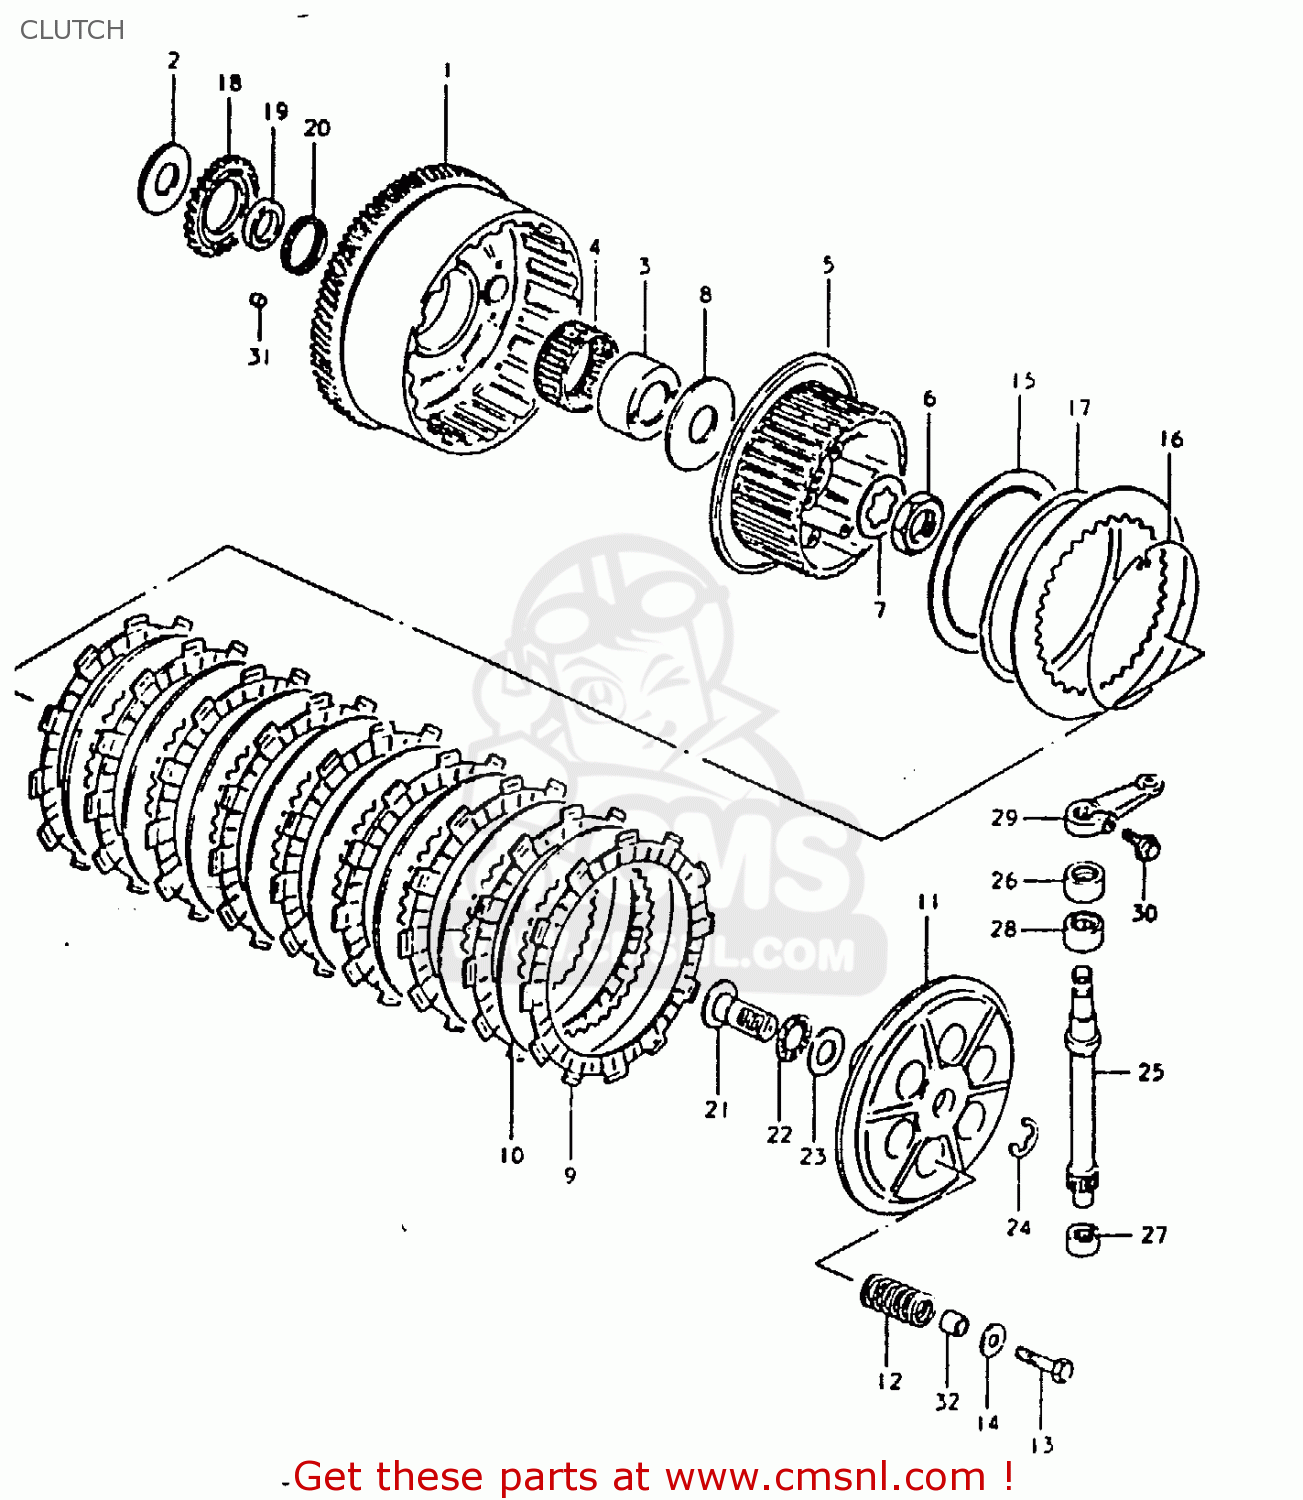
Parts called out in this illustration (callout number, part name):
1	GEAR ASSEMBLY,PRIMARY DRIVE
2	WASHER
3	SPACER
4	BEARING
5	HUB,CLUTCH SLEEVE
6	NUT
7	WASHER,LOCK
8	WASHER(25X66X3.5)
9	PLATE,CLUTCH DRIVE (MCA)
10	PLATE,CLUTCH DRIVEN (NAS)
11	DISC,CLUTCH PRESSURE
12	SPRING
13	BOLT
14	WASHER
15	SEAT,WAVE WASHER
16	RING,STOPPER
17	WASHER
18	GEAR,OIL PUMP DRIVE
19	SPACER,OIL PUMP DRIVE GEAR
20	BEARING(36X40X10)
21	RACK,CLUTCH RELEASE
22	BEARING(15X28X2)
23	WASHER
24	E RING 12MM
25	PINION,CLUTCH RELEASE
26	OIL SEAL
27	BEARING(12X19X12)
28	BEARING(15X22X12)
29	ARM,CLUTCH RELEASE
30	BOLT,REAR
31	CUSHION,PRIMARY DRIVEN GEAR
32	SPACER
